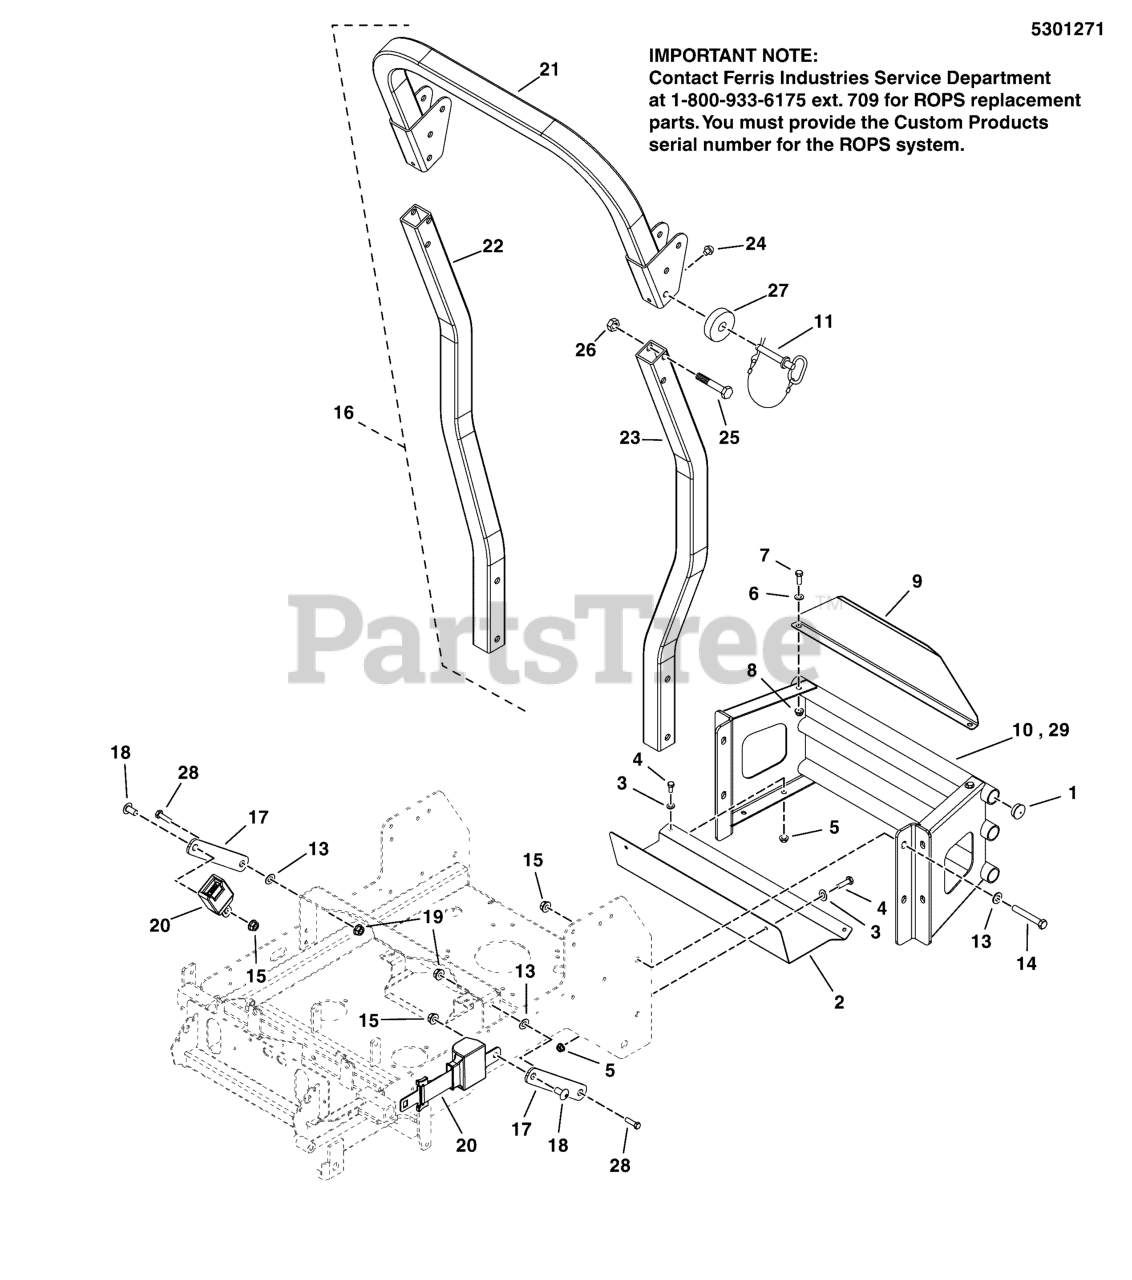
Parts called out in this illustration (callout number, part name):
1	PLUG, PANEL, 1.25 - BLACK
2	PLATE, HEAT SHIELD
3	WASHER, 5/16" SAE
4	BOLT, 5/16-18 X 3/4 GD5
5	NUT, 5/16-18 HEX NYLOCK FLANGE
6	WASHER, 3/8 SAE
7	BOLT, 3/8-16 X 1" GD5 CZ
8	NUT, 3/8-16 HEX NYLOCK FLANGE
9	PLATE, CARB PROTECTOR
10	WELD, BUMPER
11	PIN, HINGE W/ LANYARD
13	WASHER, 1/2 SAE
14	BOLT, 1/2-13 X 3-1/4, HEX HD, GD5, CZ (SV)
15	NUT, Hex Flange, Nylock, 1/2-13
16	ROPS (Call 1-800-933-6175 ext. 2193 if replacing a ROPS)
17	PLATE, SEAT BELT ANCHOR - BLK
18	SCREW, 1/2-13 X 1.00, SHCS
19	NUT, Hex Flange, Nylock, 1/2-13
20	SEAT BELT, RETRACTING - ASSM
21	ROLL BAR TOP LOOP
22	ROLL BAR POST, RH
23	ROLL BAR POST, LH
24	BUMPER, ROPS
25	BOLT
26	NUT
27	WASHER, EPDM FOAM, 1/2" ID
28	BOLT, 1/2-13 X 1-1/4 GD5 CZ
29	WELD, BUMPER - RED
